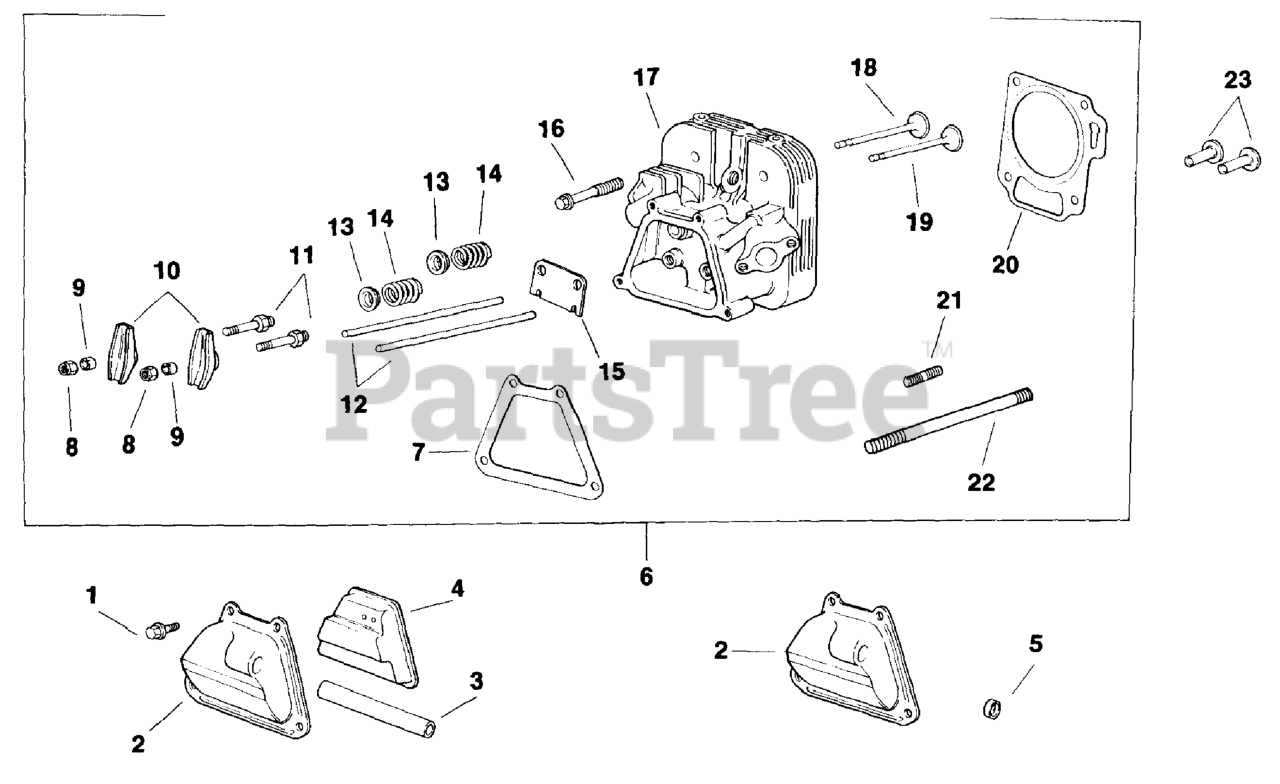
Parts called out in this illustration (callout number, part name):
1	Screw, rocker cover M6x1.0x20
6	KIT, CYLINDR HEAD - DISCONTINUED
7	GASKET, ROCKER COVER
10	ARM - DISCONTINUED
13	RETAINER - USE 15 018 06
16	SCREW, FLG M8X1.25X54
17	HEAD, CYLINDER - DISCONTINUED
18	VALVE, EXHAUST
19	VALVE, INTAKE
20	GASKET, CYL HEAD
21	Stud
22	Stud, intake
